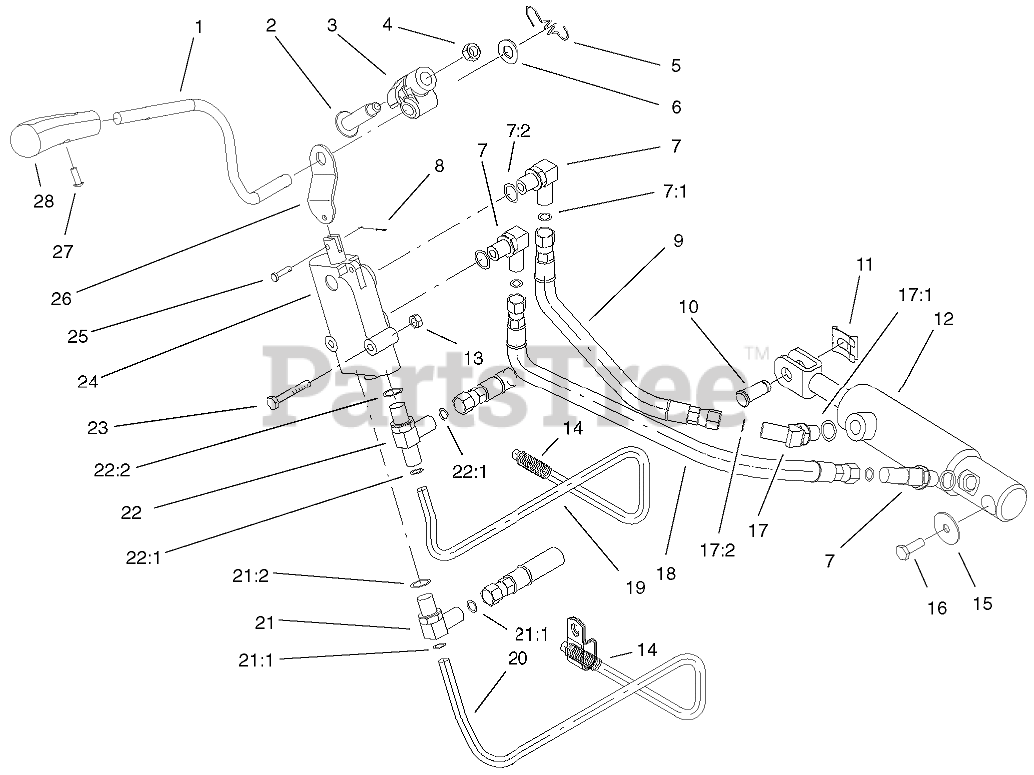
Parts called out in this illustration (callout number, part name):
1	HANDLE-LIFT
2	BOLT-SHOULDER
3	TRUNNION-LEVER, LIFT
4	NUT-JAM, LOCKING
5	SPRING-EXTENSION, LIFT
6	WASHER
7	FITTING-HYD, 90 DEGREE
7:1	O-RING
7:2	O-RING
8	PIN-COTTER
9	HOSE ASM
10	PIN-CLEVIS
11	CLIP-PIN
12	LIFT CYLINDER ASM
13	NUT-LOCK, NI
14	COVER-BRACE
15	WASHER-FLAT
16	SCREW-THREAD LOCKING
17	FITTING-HYD, 45 DEGREE
17:1	O-RING
17:2	O-RING
18	HOSE ASM
19	TUBE-HYD
20	TUBE - HYDRAULIC
21	FITTING-HYD. STRAIGHT
21:1	O-RING
21:2	O-RING
22	FITTING-HYD, LONG
22:1	O-RING
22:2	O-RING
23	SCREW-HH
24	VALVE - HYDRO LIFT
25	PIN-CLEVIS
26	LINK-LIFT
27	SCREW-PPHTF
28	Knob-Lift (only on: 73570)
28	Knob-Lift (only on: 73471, 73542)
